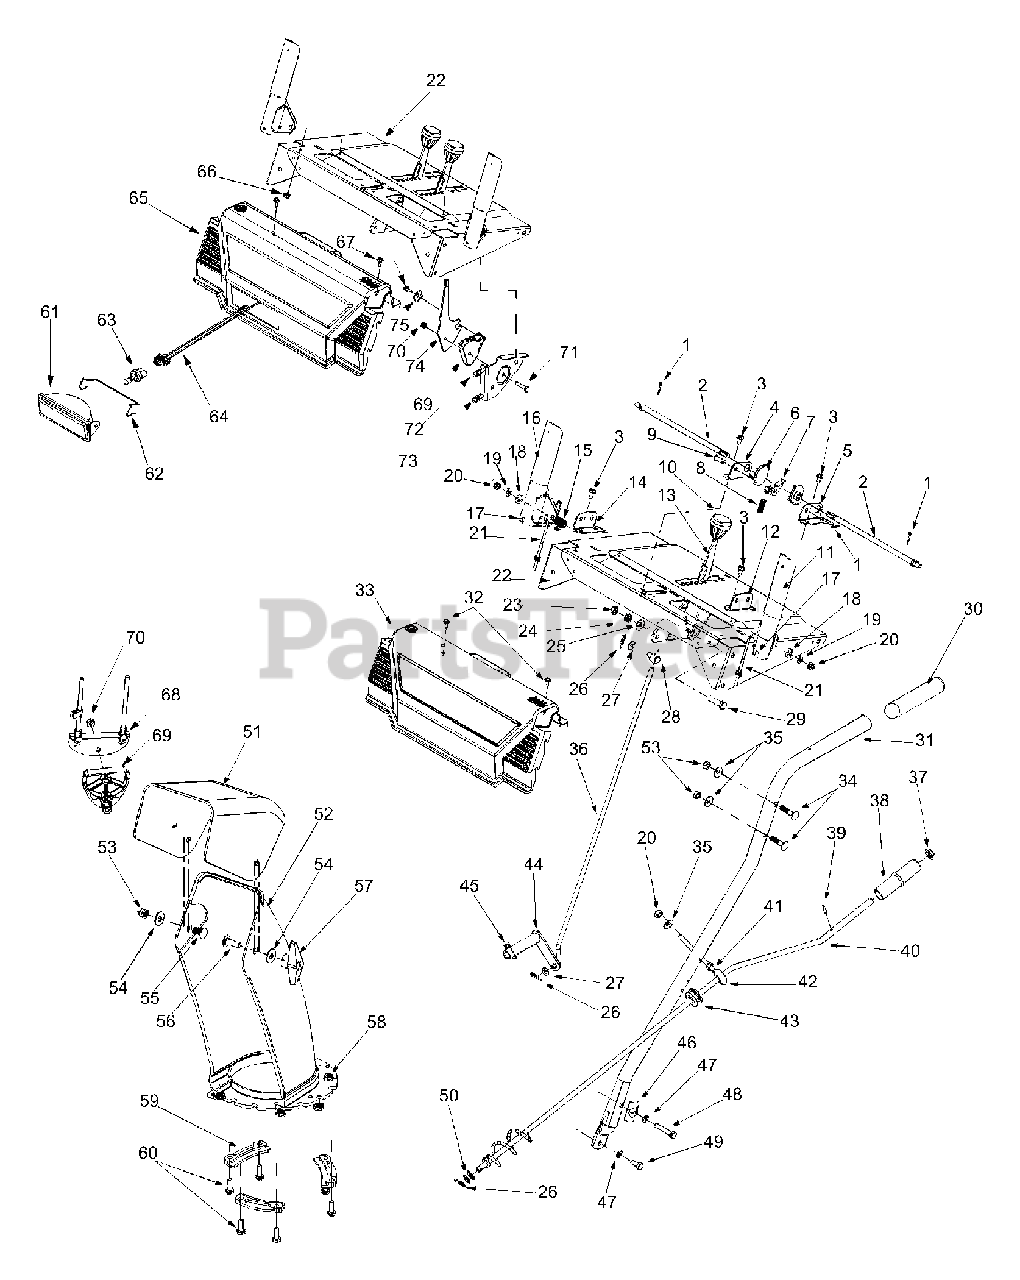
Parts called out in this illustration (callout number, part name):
1	Cotter Pin
3	Hex Washer Screw 1/4-20 x .5
7	Handle Lock Pawl
8	Compression Spring
9	Clevis Pin
10	Knob
11	Handle Assy - LH
15	Torsion Spring
16	Handle Assy - RH
17	Rubber Bumper
18	Washer
19	Lock Washer 5/16
20	Hex Nut 5/16-18
21	"Z" Fittings For Control Cables
23	Jam Lock Nut 3/8-24
24	Compression Spring
25	Bell Washer
26	Cotter Pin
27	Flat Washer 5/16
28	Ferrule
29	Hex Cap Screw 3/8-24 x 1.50
33	Handle Panel
34	Carriage Bolt 5/16-18 x 1.50
35	Bell Washer .340 ID x .872 OD
36	Shift Rod
37	Push Cap
38	Chute Knob
39	Roll Pin
40	Chute Crank
42	Chute Crank Eyebolt
43	Rubber Grommet
46	Handle Tab
47	Lock Washer 5/16
48	Hex Cap Screw 5/16-18 x 1.75
49	Hex Cap Screw 5/16-18 x .75
50	Flat Washer
51	Upper Chute
52	Lower Chute
53	Hex Lock Nut 5/16-18
54	5/16 Washer
55	Carriage Bolt 5/16-18 x .75
56	Carriage Screw 5/16-18 x 1.0
58	Hex Lock Nut 1/4-20
59	Flange Keeper
60	Hex Cap Screw 1/4-20 x .75
61	Lens Housing Assembly
62	Headlight Retaining Wire
63	Halogen Light
64	Light Harness
65	Panel w/ Light
66	Hex Nut 1/4-20
67	Hex Washer Screw #10-16 x .625
69	Chute Tilt Cable Guide
70	Lock Nut
71	Hex Bolt 5/16-18 x 1.5"
72	Chute Control Cable
73	Chute Deflector Control Cable w/Clip
75	Special Washer
